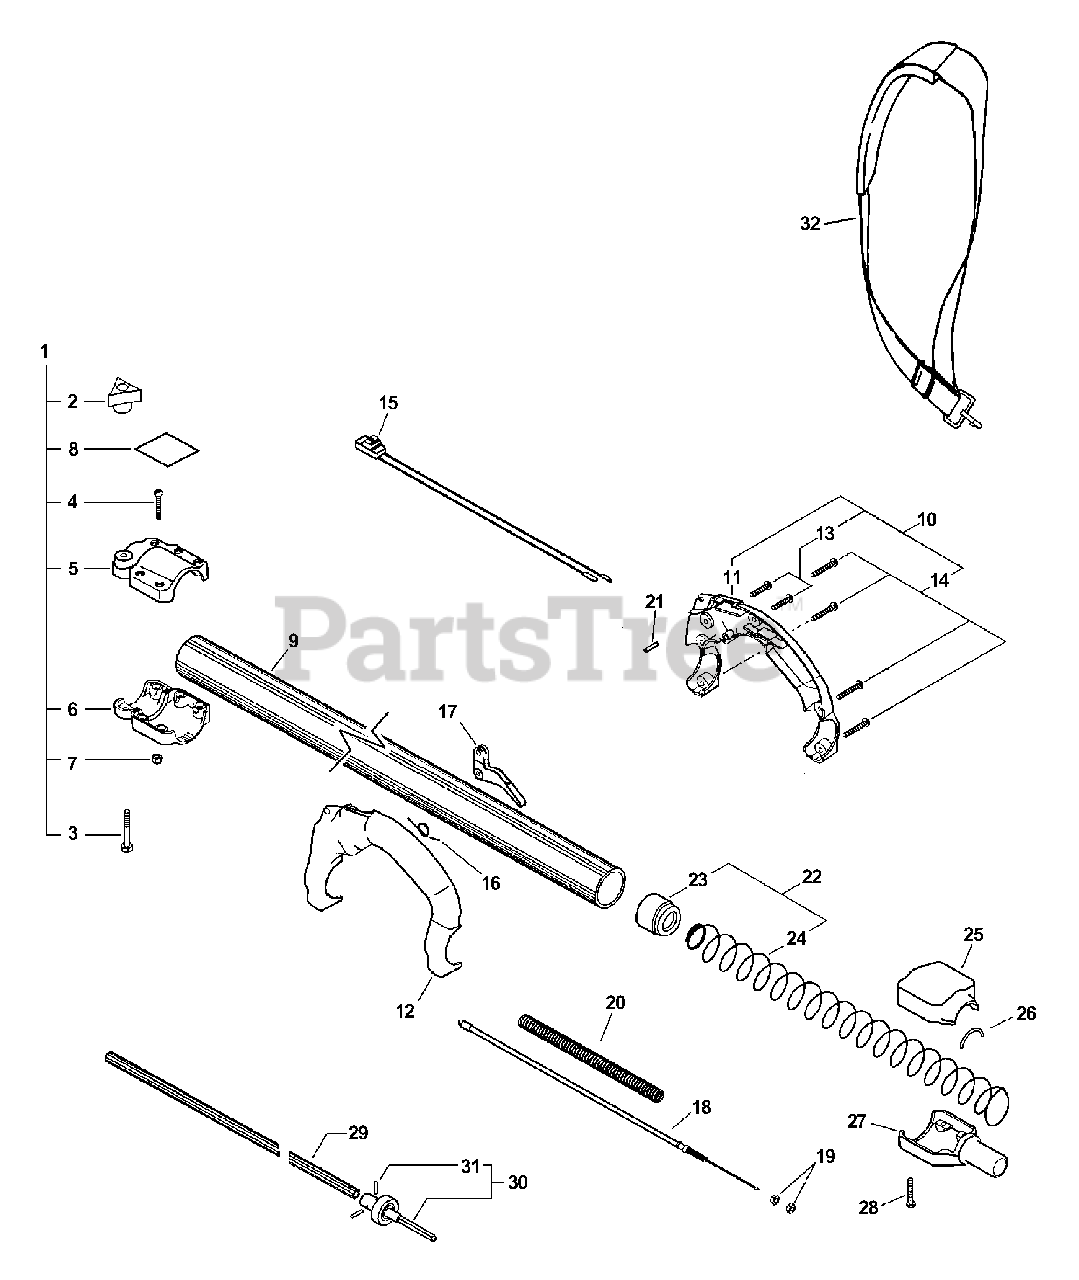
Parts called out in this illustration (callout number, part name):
1	COLLAR ASSY
2	THUMBSCREW
3	SCREW - 1/4-20 X 1-3/4"
4	SCREW - 10-24 X 1-1/4"
5	COLLAR, MAIN PIPE - UPPER
6	COLLAR, MAIN PIPE - LOWER
7	LOCKNUT - 10-24
8	LABEL - CAUTION
9	PIPE, MAIN - ORANGE
10	HANDLE ASSY - REAR
11	HANDLE, REAR - RIGHT
12	HANDLE, REAR - LEFT
13	SCREW - 10-24 X 7/8"
14	SCREW - 10-24 X 1-1/4"
15	IGNITION SWITCH ASSY
16	SPRING, TRIGGER
17	TRIGGER, THROTTLE
18	CABLE, THROTTLE
20	TUBE, PROTECTIVE - CORRUGATED
21	PIN - LOCATING
22	FLOATING BUSHING ASSY
23	BUSHING, FLOATING
25	LOWER HSNG ADAPT (TOP)
27	ADAPTER - LOWER
28	SCREW - 10-24 X 1-1/4"
29	DRIVESHAFT
30	SHAFT CONNECTOR KIT
32	SHOULDER STRAP ASSY
